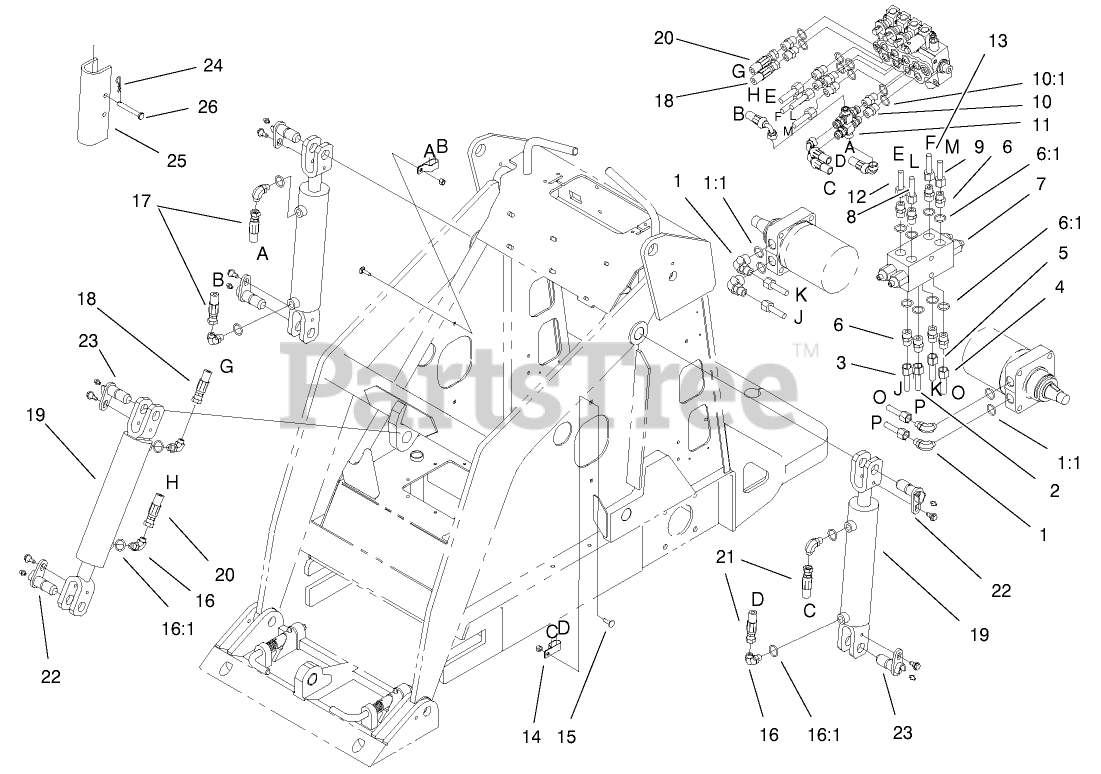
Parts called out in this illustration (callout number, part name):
1	FITTING-ELBOW, 90 DEG
1:1	O-RING
2	TUBE-HYD
3	TUBE-HYD.
4	TUBE-HYD.
5	TUBE-HYD.
6	FITTING-STRAIGHT
6:1	O-RING
7	VALVE-COUNTERBALANCE
8	TUBE-HYD
9	TUBE-HYD.
10	FITTING
10:1	O-RING
11	CONNECTOR-SWIVEL
12	TUBE-HYD
13	TUBE-HYD
14	CLAMP-R, DOUBLE
15	BOLT-CARR
16	FITTING-ELBOW, 90 DEG
16:1	O-RING
17	HOSE-HYD
18	HOSE-HYD
19	Hydraulic Cylinder
20	HOSE-HYD
21	HOSE-HYD
22	ASM - PIVOT PIN, AU
23	ASM - PIVOT PIN, AU
24	PIN-HAIR
25	Lock-Cylinder
26	PIN-CLEVIS
